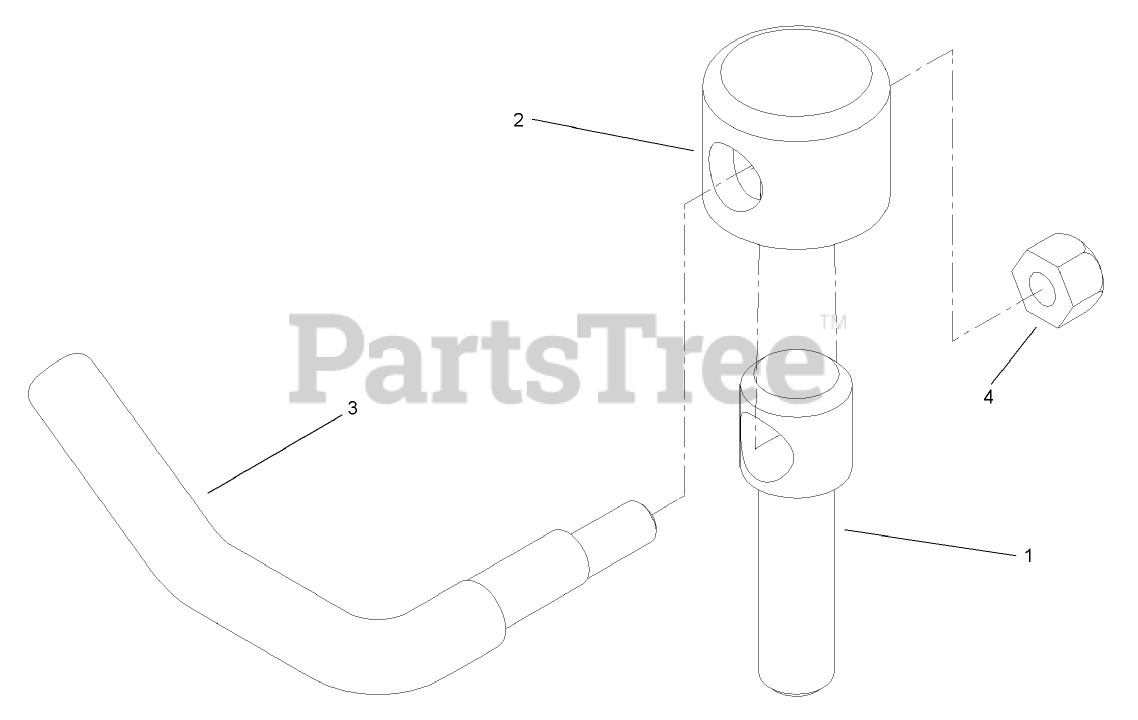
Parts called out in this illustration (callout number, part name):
1	Screw-Lock
2	Cap-Lock
3	Lever-Lock
4	NUT-LOCK, NI
